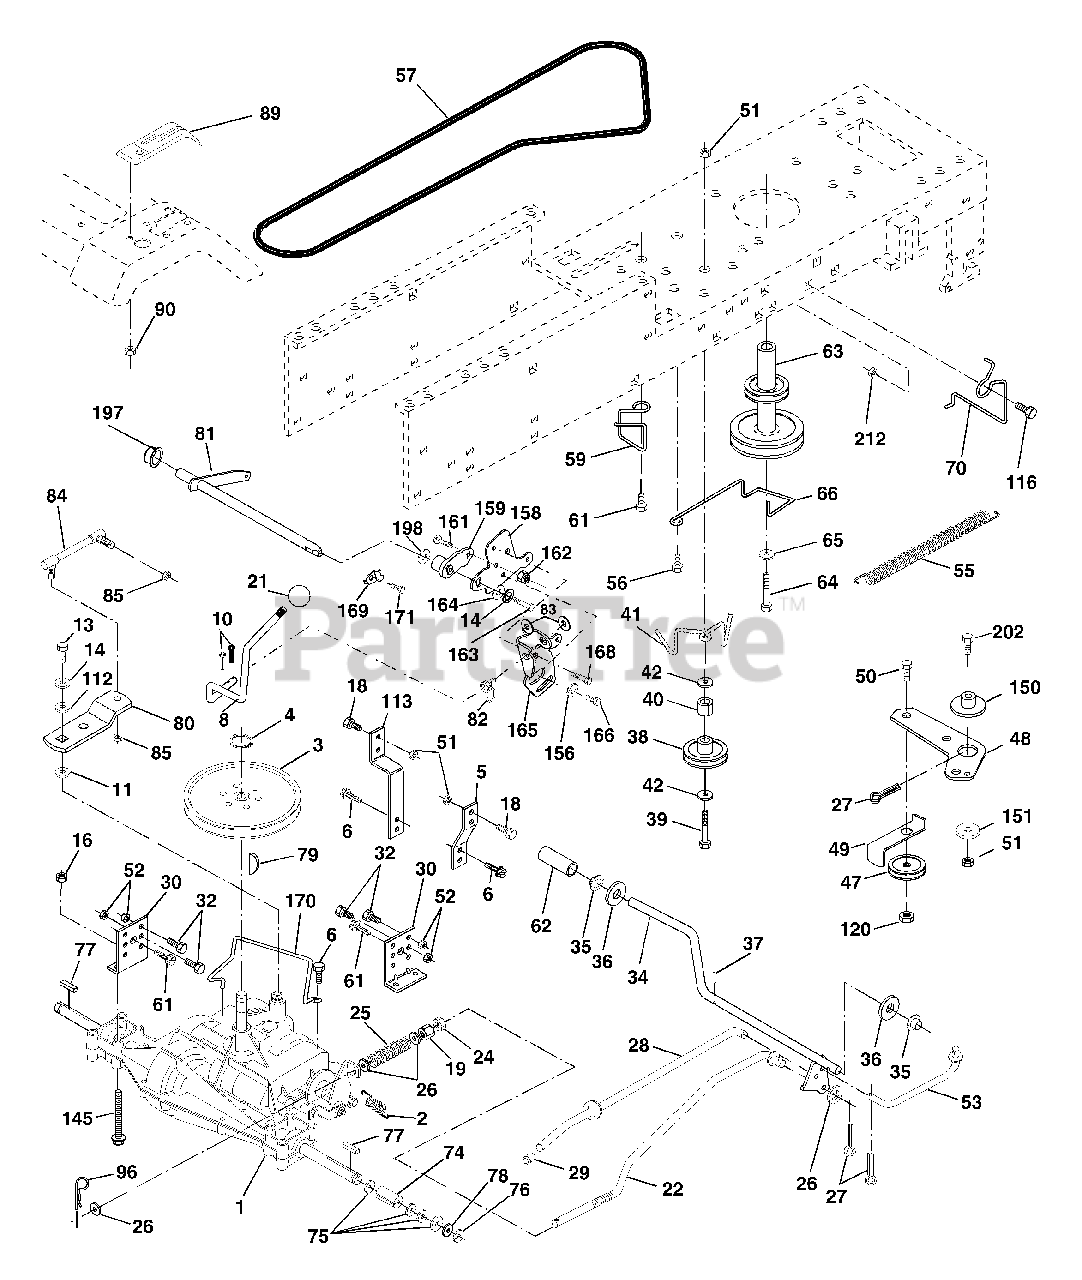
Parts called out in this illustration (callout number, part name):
2	Spring Return Brake T/a Zinc
3	Pulley Transaxle 18" tires
4	Ring Retainer #5100-62
5	Strap Torque 30 Degrees
6	Screw 5/16-18 x 3/4
8	Rod Shifter Fender Adj Lt
10	Pin Cotter 1/8 x 1 Cad
11	Washer Plate Shf 388 Sq Hole
13	Bolt 1/4-28 Unf Gr 8 W/Patch
14	Washer Lock Hvy Helical 1/4
16	Nut Lock
18	Bolt, Fin Hex 3/8-16 UNC x 1 Gr. 5
19	Nut Lock 3/8-16 Unc
21	Knob
22	Rod Brake Blk Zinc 26 840
24	Nut Hex Jam 3/8-16 Unc
25	Spring Rod Brake 2 00 Zinc
26	Washer 13/32 X 13/16 X 16 Ga
27	Pin Cotter 1/8 X 3/4 Cad
28	Rod Brake Parking LT/YT
29	Cap Brake Parking
30	Bracket Mtg Transaxle
32	Bolt Hex Hd 5/16-18unc X 3/4
34	Shaft Asm Pedal Foot
35	Bearing Nylon Blk 629 Id
36	Washer 21/32 X 1 X 16 Ga
37	Pin Roll 3/16 X 1"
38	Pulley Idler Flat
39	Bolt Fin Hex 3/8-16unc X 3
40	Spacer Split
41	Keeper Belt Retainer Idler
42	Washer 13/32 X 13/16 X 12 Ga
47	Pulley Idler V Groove Plastic
48	Bellcrank Asm
49	Retainer Belt Style Spring
50	Bolt Hex Hd 3/8-16unc X 1-1/2
51	Nut Crownlock 3/8-16 Unc
52	Nut Crownlock 5/16-18 Unc
53	Link Clutch
55	Spring Return Clutch 6 75
56	Bolt Fin Hx 3/8-16 X 1.00
57	V-Belt Ground Drive
59	Keeper Belt Span Ctr
61	Screw 3/8-16 x 3/4
62	Cover Pedal Blk Round
63	Engine Pulley LT/YT
64	Bolt Hex
65	Washer Lock Hvy Hlcl Spr 7/16
66	Keeper Belt Engine Foolproof
70	Guide Belt Mower Drive RH
74	Spacer Axle
75	Washer 25/32 X 1 1/4 X 16 Ga
76	E-ring #5133-75
77	Key Square 2 0 X 1845/ 1865
78	Washer 25/32 X 1-5/8 X 16 Ga
79	Key Woodruff
80	Arm Shift
81	Shaft Asm Cross Tapered 20"t
82	Spring Torsion T/a
83	Washer 17/32 X 3/4 X 16 Ga
84	Link Transaxle
85	Nut Lock Center 1/4 - 28 FNTHD
90	Nut Self-thd Wsh-hd 1/4 Zinc
96	Retainer Spring
112	Washer 9/32 x 3/4 x 10 Ga.
113	Strap Torque Lh
116	Bolt Rdhd Sq Neck 3/8-16 x 1
120	Nut Lock 3/8-16
145	Bolt Hex 5/16-18 Gr. 5
150	Spacer
151	Washer 13/32 x 2 x 10
156	Washer Srrted 5/16 ID x 1.125
158	Bracket Shift Mount
159	Hub Tapered Flange Shift lt
161	Bolt Rdhd Sqnk 1/4-20 x 3/4 Gr 5
162	Nut Crownlock 1/4-20 Unc
163	Bolt Hex Fin 1/4-20 Unc x 1 Gr 5
164	Washer 5/8 x .281 x 10 Ga
165	Bracket Pivot Lever
166	Screw 5/16-18 x 5/8
168	Bolt Shoulder 5/16-18 x .561
169	Plate Fastening Lt
170	Keeper Belt Transaxle
171	Screw Thdrol 3/8-16 x 1/2
197	Nyliner, Snap - in
198	Washer, Nyl.
202	Bolt, Carriage 3/8 - 16 x 1 3/4
212	Nut Hex Flange Lock
